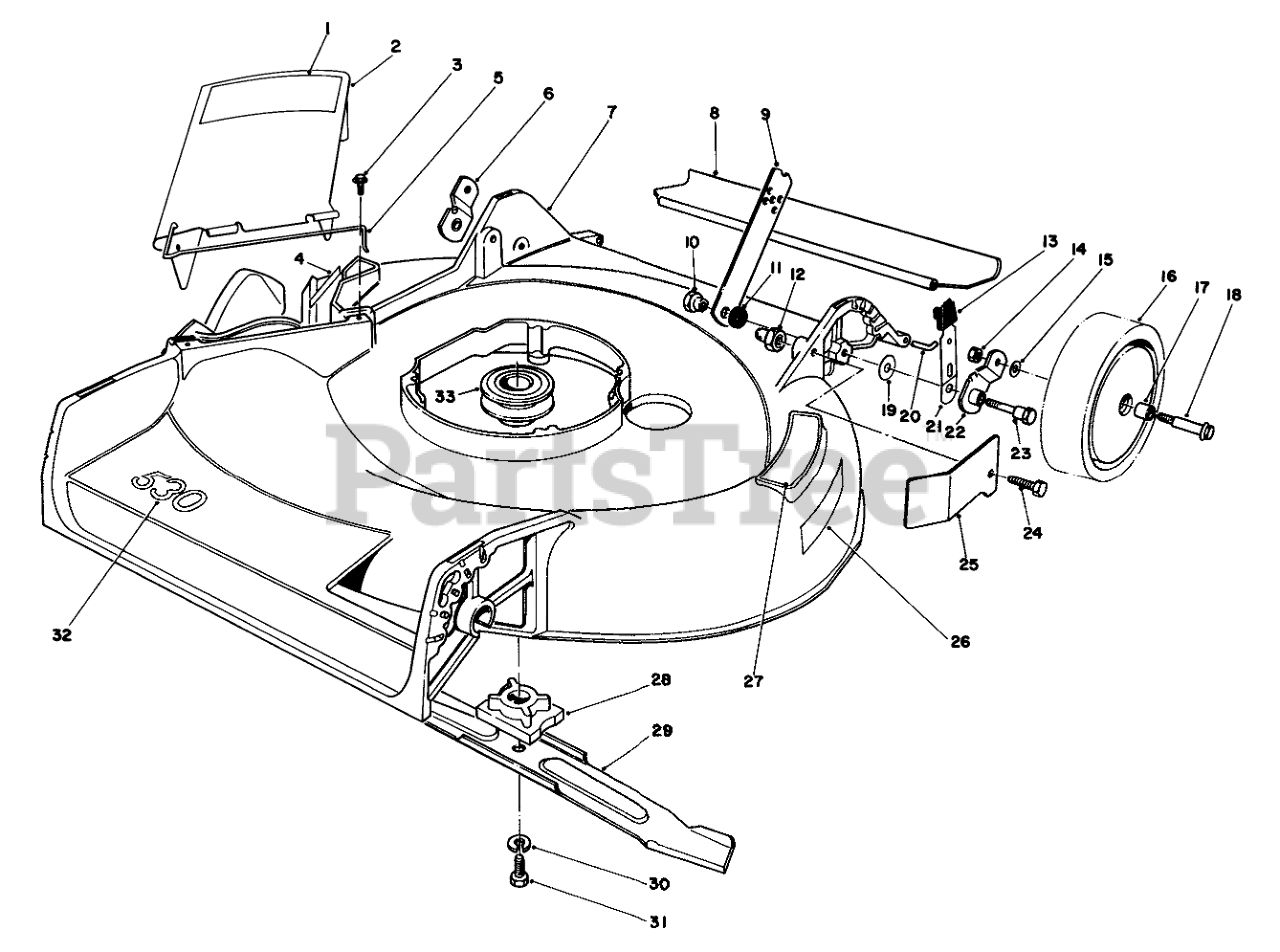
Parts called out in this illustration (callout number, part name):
1	DANGER DECAL
2	Deflector Cover Assembly (Incl. Ref. #1 & 5)
3	SCREW-HWH
4	Decal-Danger
5	SPRING HINGE
6	Pivot Arm
7	Housing (Incl. Ref. #26)
8	Rear Shield
9	HANDLE LATCH
10	HANDLE PIVOT NUT
11	SPACER
12	HANDLE PIVOT NUT
13	KNOB-ARM
14	NUT-LOCK
15	WASHER
16	Wheel & Tire Assembly (Incl. Ref. #17)
17	BUSHING
18	WHEEL BOLT
19	WASHER-PIVOT
20	SHIELD ROD
21	SPRING ARM ASM
22	Pivot Arm
23	PIVOT SCREW
24	SCREW-HH
25	MUFFLER SHIELD
26	Decal-Place Foot Here
27	STEP PAD DECAL
28	BLADE RETAINER
29	Blade
30	WASHER-LOCK
31	SCREW-HH
32	Decal-530
33	Pulley
